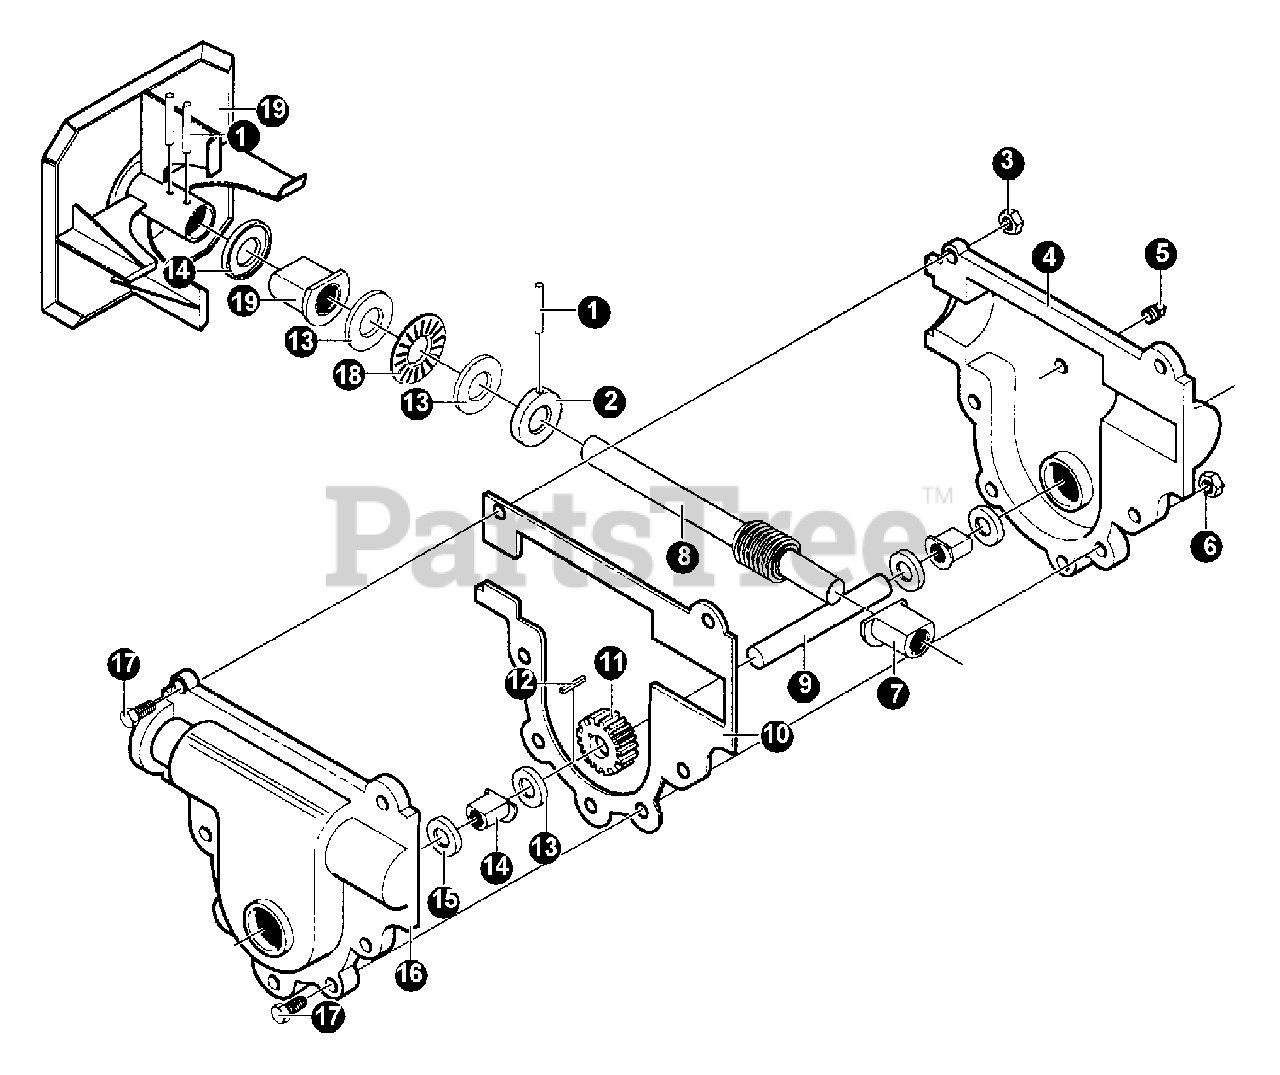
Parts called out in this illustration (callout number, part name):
1	PIN - SPRING - .250DIAX1.25LG
2	COLLAR, THRUST .753X1.24X.50
3	NUT - 1/4-20 -- KEPS
4	CASE, GEAR - LEFT
5	SCREW - 3/8-16 X .50"
6	LOCKNUT - 1/4-20
7	BEARING, FLANGE
8	SHAFT, WORM
9	SHAFT, AUGER OUTPUT
10	GASKET, GEAR CASE
11	GEAR - WORM
12	KEY - 61
13	WASHER - .752X1.24X.093
14	BEARING, FLANGE
15	SEAL, OIL
16	CASE, GEAR - RIGHT
17	SCREW - 1/4-20
18	BEARING, ROLLER
19	IMPELLER ASSY
